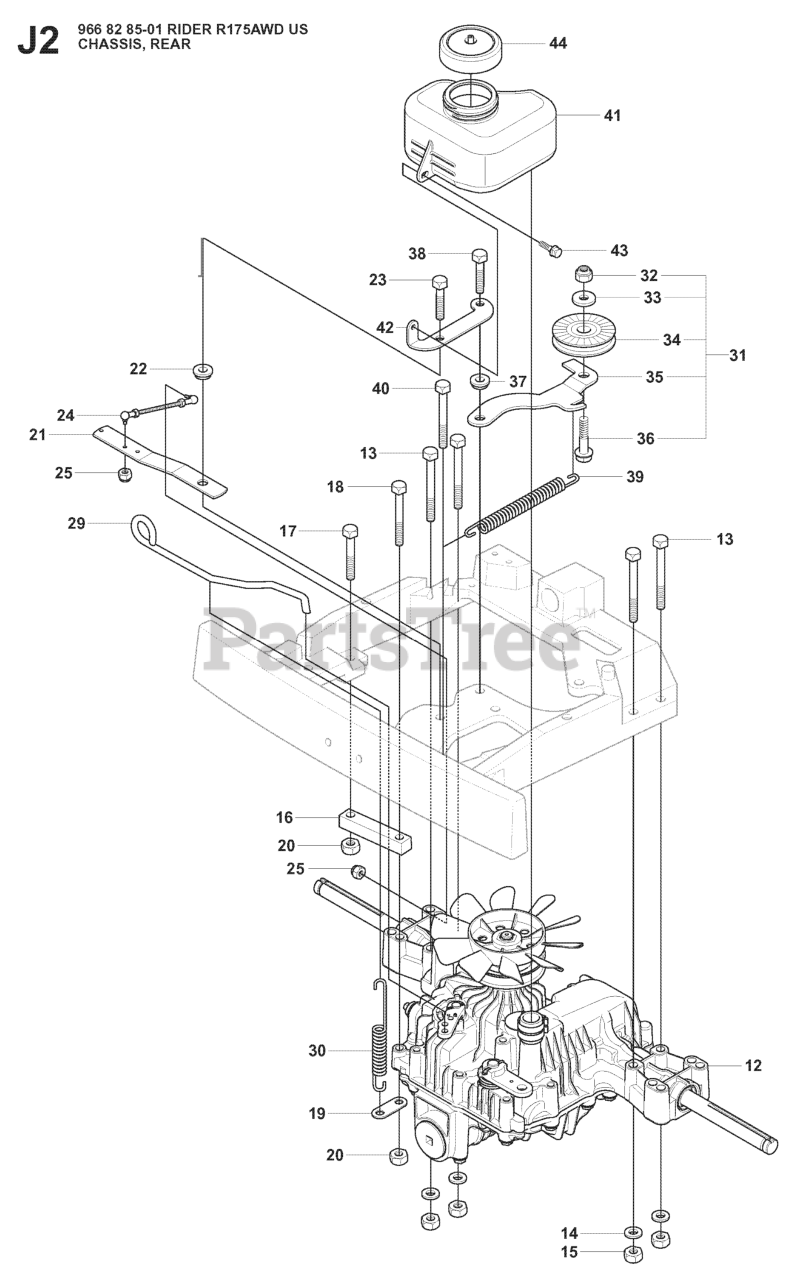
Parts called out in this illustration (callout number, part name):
12	HYDRAULMOTOR
14	WASHER BRB 8.4X17
15	NUT
20	NUT
22	WASHER
23	SCREW 8X20
25	LOCKNUT M5
32	TENSIONER
34	SCREW
36	LOCKNUT M8
37	WASHER
38	SCREW 8X20
